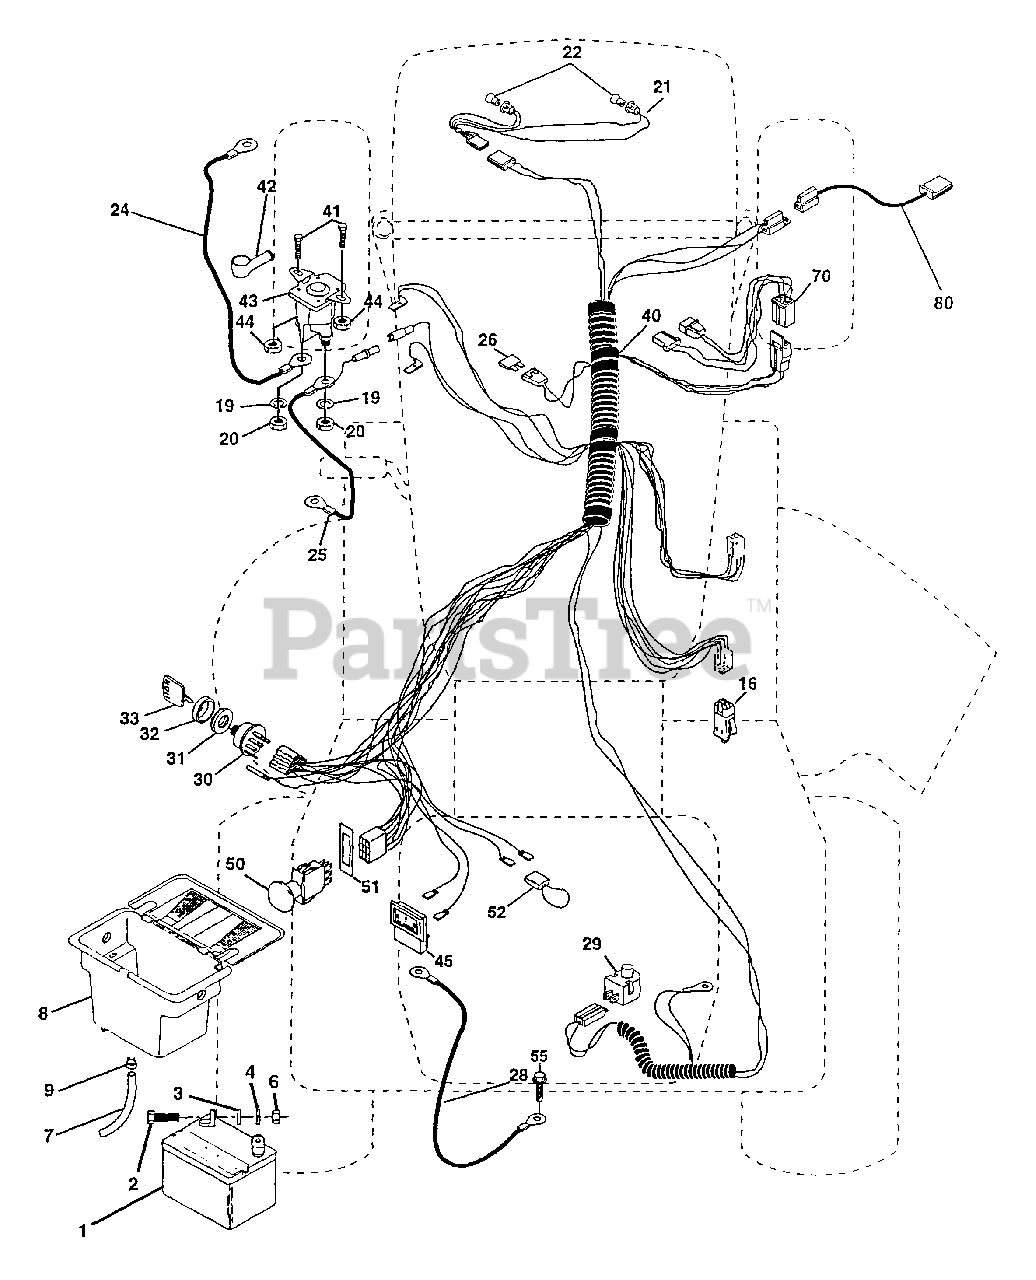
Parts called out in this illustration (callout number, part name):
1	Battery 12 Volt 30 AMP (AYP part number)
2	Bolt Hex Hd 1/4-20 UNC X 3/4
3	Washer 9/32 X 5/8 X 16 Ga.
4	Washer Lock Hvy Helical 1/4
6	Nut Fin Hex 1/4-20 UNC
7	Tube Plastic 12"
8	Case Battery Mech Hinge
9	Clamp Hose Olive
16	Switch Interlock Push-In (AYP part number)
19	Washer Lock 1/4 (AYP part number)
20	Nut Jam Hex 1/4-20 UNC
21	Harness Asm Light W/4152j
22	Bulb Light #1156
24	Cable Battery 6 Ga 11" red
25	Cable Battery 6 Ga 44" red w/16 wire
26	Fuse 30 AMP Auto Green
28	Cable Ground 6 Ga 12" black
29	Switch Plunger Nc Gray
30	Switch Ign 4 pos w/Lights
31	Nut Ignition
32	Cover Sw Ignition
33	Key Ign Molded Indak
40	Harness Ign.
41	Bolt Blk Fin Hex 1/4-20 x 1/2
42	Cover Terminal Red
43	Solenoid (AYP part number)
44	Nut Keps Hex 1/4-20 UNC
45	Ammeter Rectangular 6 amp (AYP part number)
50	Switch, PTO 3 PDT Black Delta 96
51	Ring Retainer PTO
52	Protection Wire Loop
70	Harness, Eng. B & S 14 OHV Dual
80	Harness, Clutch EVX
